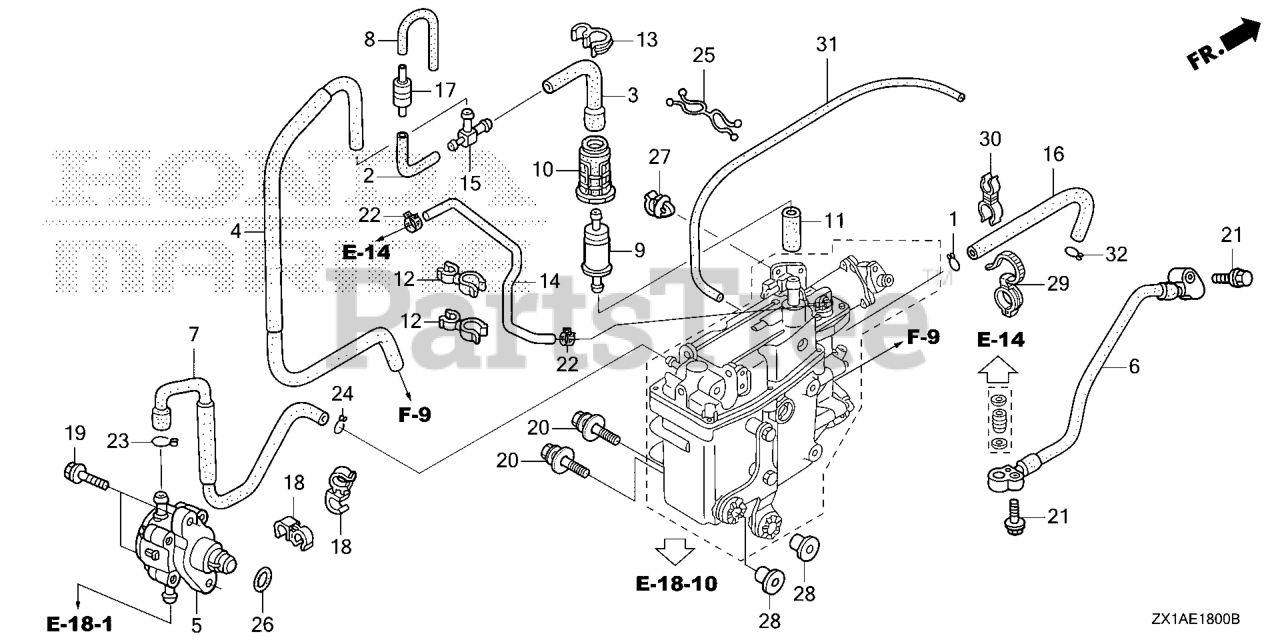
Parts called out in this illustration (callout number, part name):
1	CLIP, TUBE (ENGINE NO.)
2	TUBE C, AIR VENT
3	TUBE B, AIR VENT
4	TUBE, AIR VENT
5	PUMP ASSY., FUEL (MSDS)
6	HOSE, FUEL
7	TUBE B, FUEL
8	TUBE D, FUEL
9	FILTER, FUEL PUMP
10	SUSPENSION, STRAINER
11	TUBE B, FUEL
12	CLAMP, HOSE
13	CLAMP, PIPE
14	HOSE, PRESSURE REGULATOR RETURN
16	TUBE G, WATER
17	VALVE, CHECK
18	CLIP, SENSOR HOSE
19	BOLT, FLANGE (6X27)
20	BOLT-WASHER (8X35)
21	BOLT, FLANGE (6X25)
22	CLAMP, TUBE (D10.7)
23	CLIP, TUBE (B1 14.5)
24	CLIP, TUBE (B12)
25	CLIP, FUEL HOSE
26	O-RING (33.2X2.4) (NOK)
27	CLIP, HARNESS
28	COLLAR (8.5X14.5)
29	CLIP, TUBE (135MM) (BLACK)
30	CLAMP, PURGE HOSE (NOT AVAILABLE)
31	BULK HOSE, FUEL (3.5X3000) (3.5X120)
32	CLIP, TUBE (B1 11)
